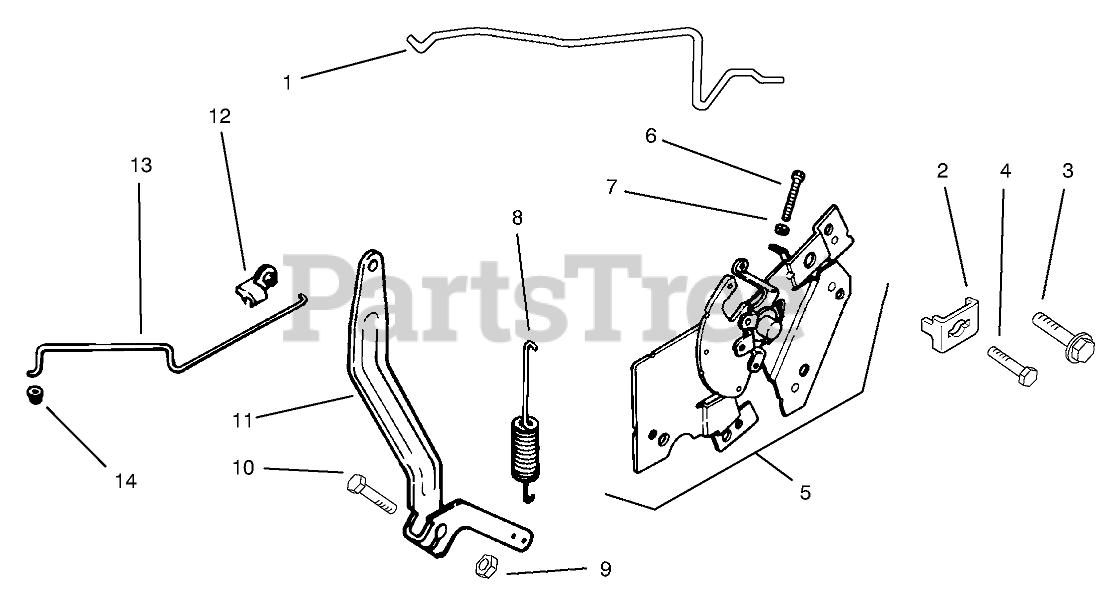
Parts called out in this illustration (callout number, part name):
1	Linkage-Choke (Only On: 92003, 92043)
2	Clamp-Cable (Only On: 92003, 92043)
3	Screw Socket (Only On: 92003, 92043)
4	Screw M5x0.8x16 (Only On: 92003, 92043)
5	Control-ASM INC 6-7 (Only On: 92003, 92043)
6	Screw-HHF M4x0.7x28 (Only On: 92003, 92043)
7	Nut-Hex M4x0.7 (Only On: 92003, 92043)
8	Spring-Governor (Only On: 92003, 92043)
9	Nut M6x1.0 (Only On: 92003, 92043)
10	Screw M6x1.0x25 (Only On: 92003, 92043)
11	Lever-Governor (Only On: 92003, 92043)
12	Bushing-Linkage (Only On: 92003, 92043)
13	Linkage-Throttle (Only On: 92003, 92043)
14	Bushing-Linkage (Only On: 92003, 92043)
